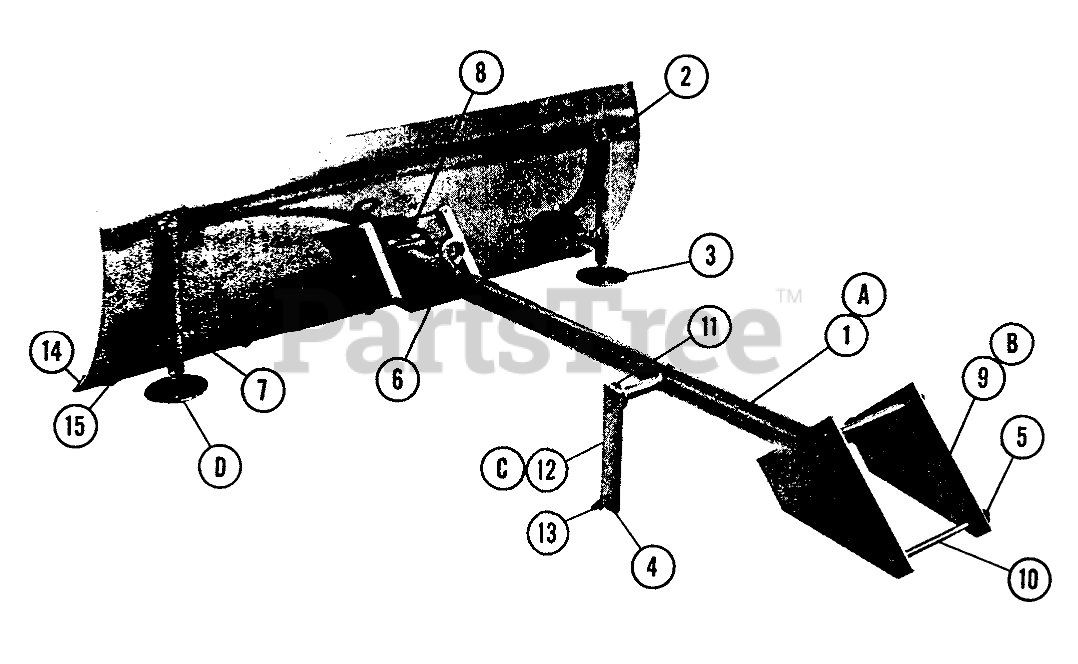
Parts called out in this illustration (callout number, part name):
1	Drive Assembly
2	Blade Assembly
3	Skid Assembly
4	Hex Nut
5	Lockwasher
6	Pin-Tool
7	Sq. Hd. Set Screw
8	HHCS, 3/8-16 x 3
9	Hanger Plate
10	Machine Bolt 3/8 x 7
11	Cotter Key
12	Lift Bar
13	Hex Head Cap Screw
14	Plate
15	Carriage Bolt, 3/8 x 3/4
